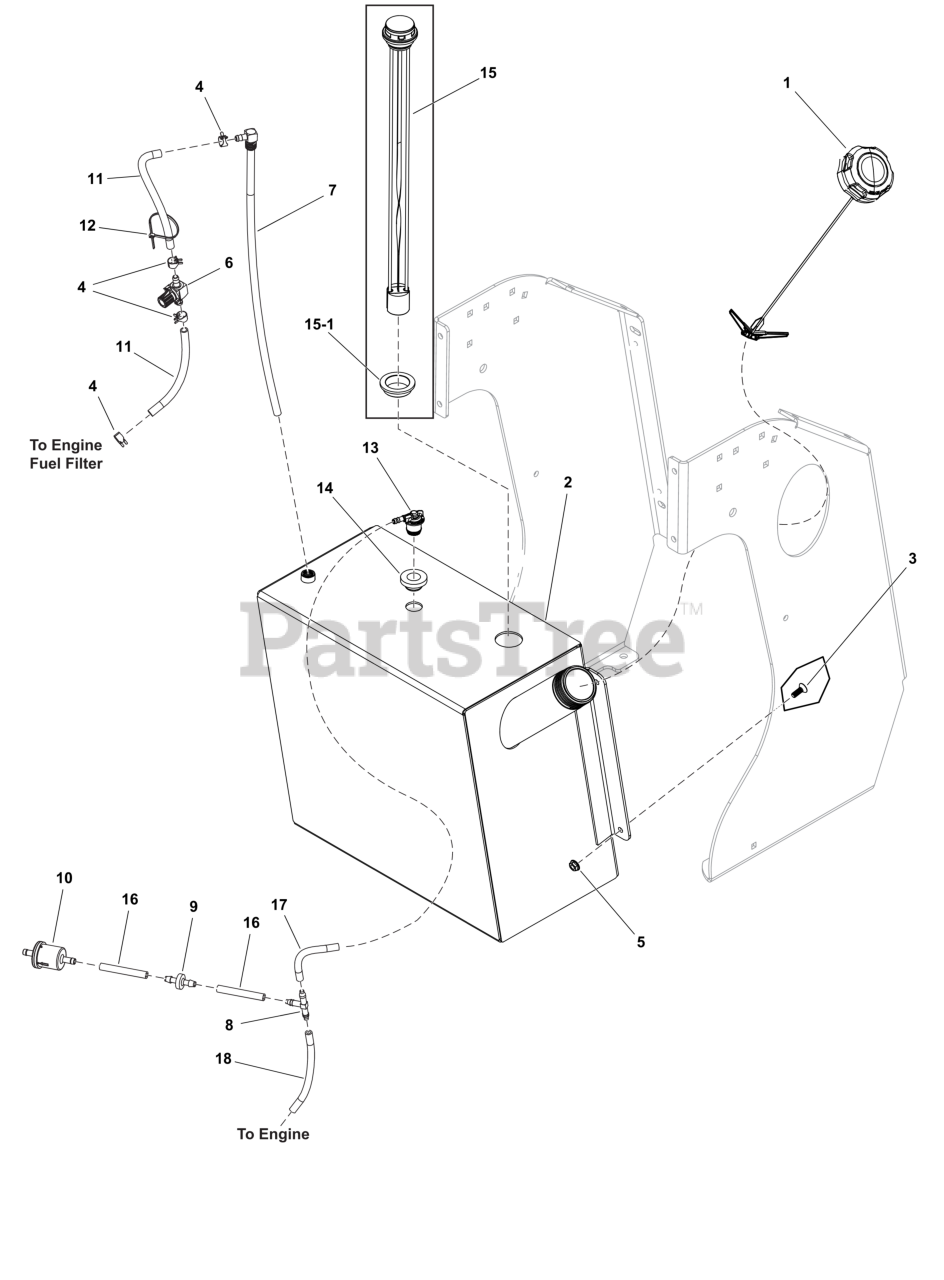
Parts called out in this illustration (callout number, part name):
1	CAP, Fuel Tank
2	TANK, Fuel
4	CLAMP, Hose
6	VALVE, Fuel Shut Off
7	EXTENSION, FUEL TRANSFER TUBE
9	VALVE, Check
10	FILTER, Fuel
11	HOSE, 1/4" FUEL, 6.00
12	TIE WRAP, 5-1/2" LONG
13	REMOTE VENT ASSEMBLY
14	GROMMET
15	GAUGE, Fuel
15-1	RUBBER SEAL
16	HOSE, VAPOR
17	HOSE, Vapor
18	HOSE-VAPOR
